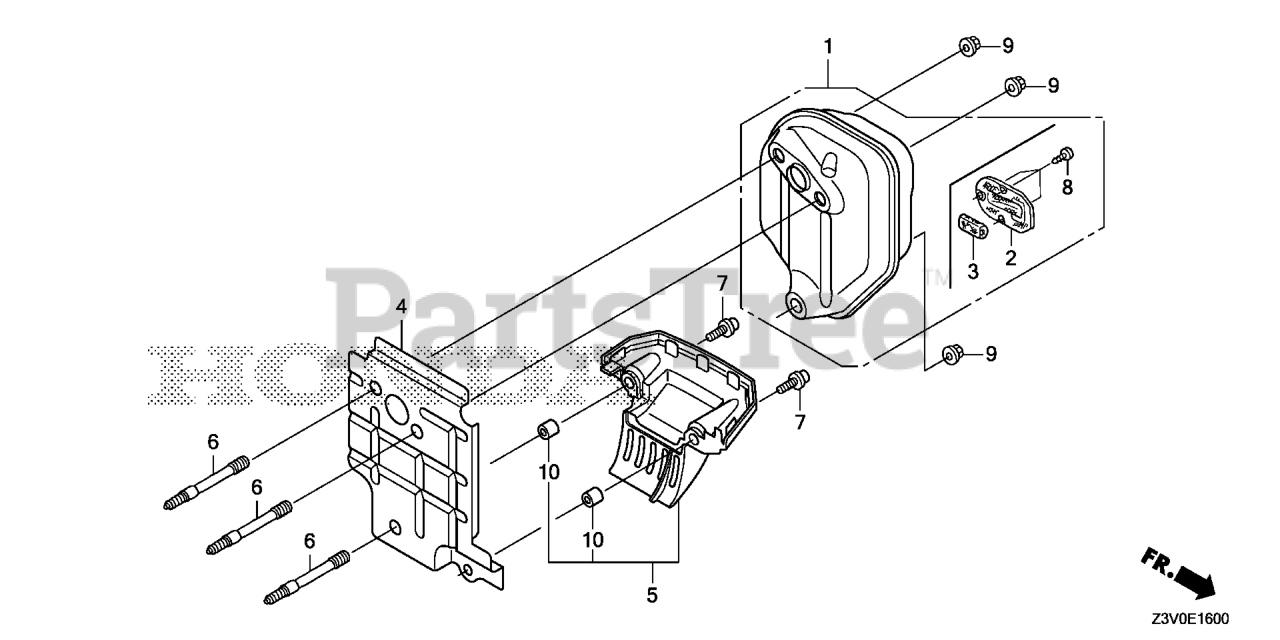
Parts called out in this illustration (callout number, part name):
2	ARRESTER, SPARK
3	FILTER, EX.
4	GUIDE, AIR
5	GUIDE, AIR (LOWER)
6	BOLT, STUD (5X56.5)
7	BOLT, SOCKET (5X16)
8	SCREW, TAPPING (4X6) (TO INSTALL OPTIONAL SPARK ARRESTER)
9	NUT, SELF-LOCK (5MM)
10	COLLAR A, HEAD COVER
